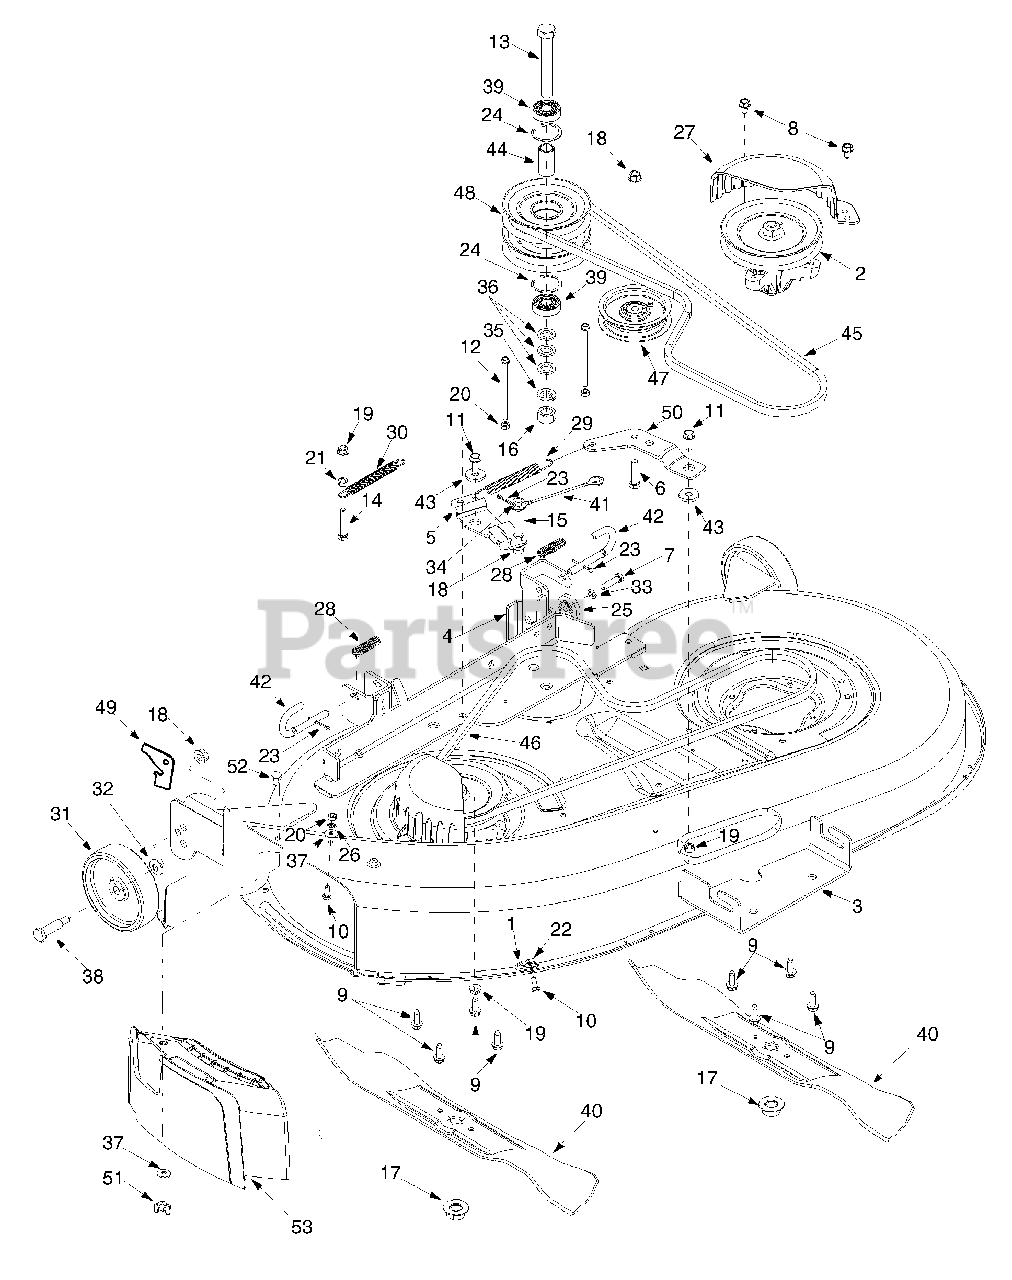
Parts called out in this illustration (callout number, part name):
1	Bracket: Retainer Hook
2	Spindle Assembly: Pulley
6	Hex Screw 3/8-16 x 1.5
7	Hex Screw 5/16-18 x 1.25
8	TT Screw 5/16-18 x 0.625
9	TT Screw 5/16-18 x 0.875
10	Hex Screw 1/4-20 x 0.620
11	Hex Washer Head Screw
12	TT Screw 1/4-20 x 4.0
13	Hex Screw 5/8-18 x 4.25
14	Hex Screw 5/16-18 x 1.75
16	Hex Nut 5/8-18
17	Flange Nut 5/8-18
18	Flange Lock Nut
19	Flange Lock Nut
20	Hex Nut 1/4-20
21	Hex Nut 5/16-18
22	Lock Nut 1/4-20
23	Cotter Pin
24	Snap Ring
25	Gear: Deck Adjustment
27	Belt Cover
28	Compression Spring
29	Extension Spring
30	Extension Spring
31	Deck Wheel
32	Bell Washer
33	Lock Washer
34	Flat Washer
35	Lock Washer
36	Flat Washer
37	Bell Washer
38	Sholder Spacer
39	Bearing
40	Blade
41	Brake Cable
42	Deck Release Rod
43	Shoulder Spacer
44	Spacer
45	V-Belt
46	V-Belt
47	Idler Pulley
48	Double Pulley
49	Chute Stop
52	Carriage Screw
53	Mulch Plug
